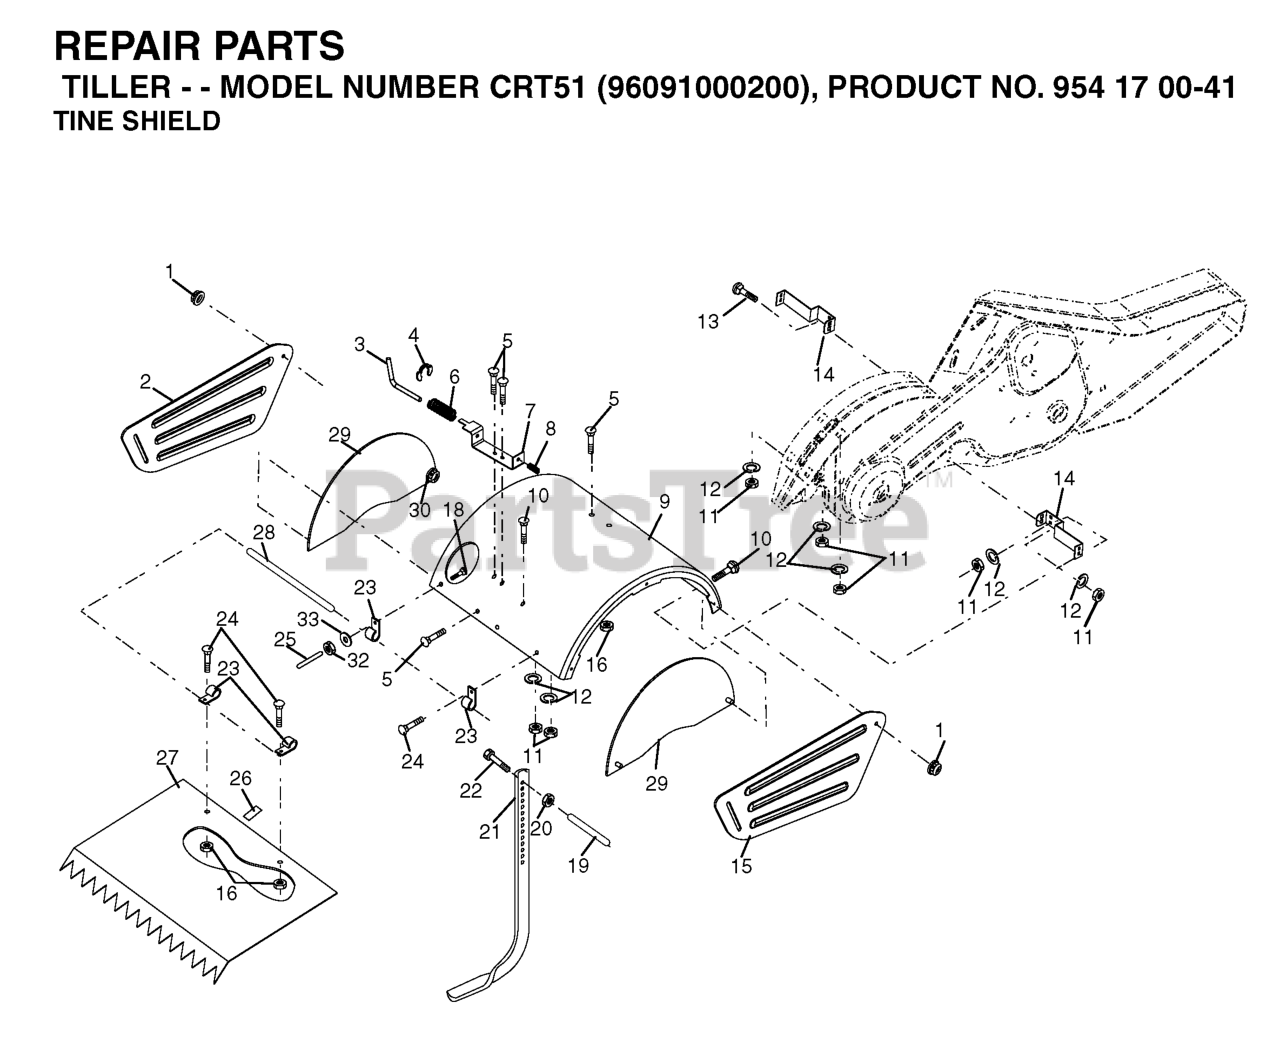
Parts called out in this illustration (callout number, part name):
1	NUT LOCK HEX FLANGE 5/16-18
2	SHIELD
3	STAKE PIN TI
4	RING, KLIP
5	BOLT, RDHD SQNK 5/16-18 X 3/4
7	BRACKET.LATCH.STAKE.3.20.BLACK
8	SPRING CRT
9	SHIELD
12	WASHER.LOCK.HVY.HLCL.SPR.5/16
13	BOLT.CARRIAGE.5/16-18
14	BRACKET.TINE.SHIELD.TILLER.BLA
15	SIDE SHIELD RH
16	NUT T
20	NUT.HEX.3/8-16UNC
21	STAKE.DEPTH.16.CRT.BLACK
22	BOLT.375-16
25	VINYL CAP TI
26	PAD IDLER TI
27	SHIELD LEVELING
28	PIN.HINGE.TILLER
29	SHIELD.ASM.SIDE.ORANGE.(OLD)
30	LOCKNUT-FLANGE 5/16-18
32	NUT
33	LOCKWASHER
35	BOLT.CARR.5/16-18X5/8.SHORT
37	NUT.71038.31-18.HEX.NYLOCK
